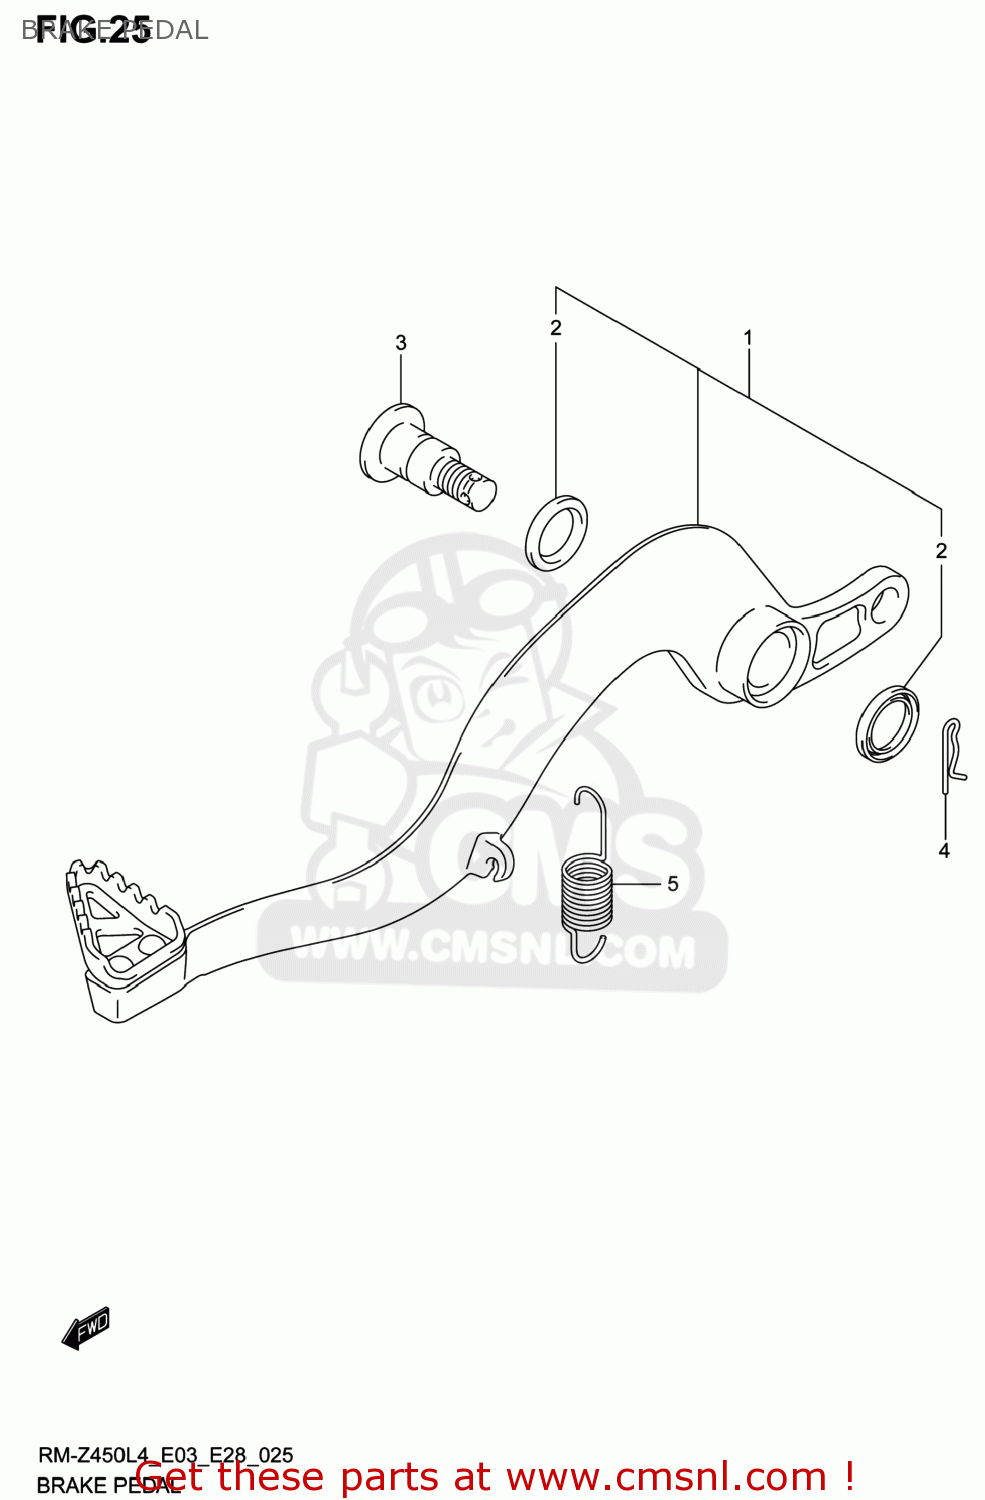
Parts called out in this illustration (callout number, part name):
1	PEDAL ASSY,BRAKE
2	SEAL,OIL(15X21X3)
3	SHAFT,BRAKE PEDAL
4	CLIP
5	SPRING
